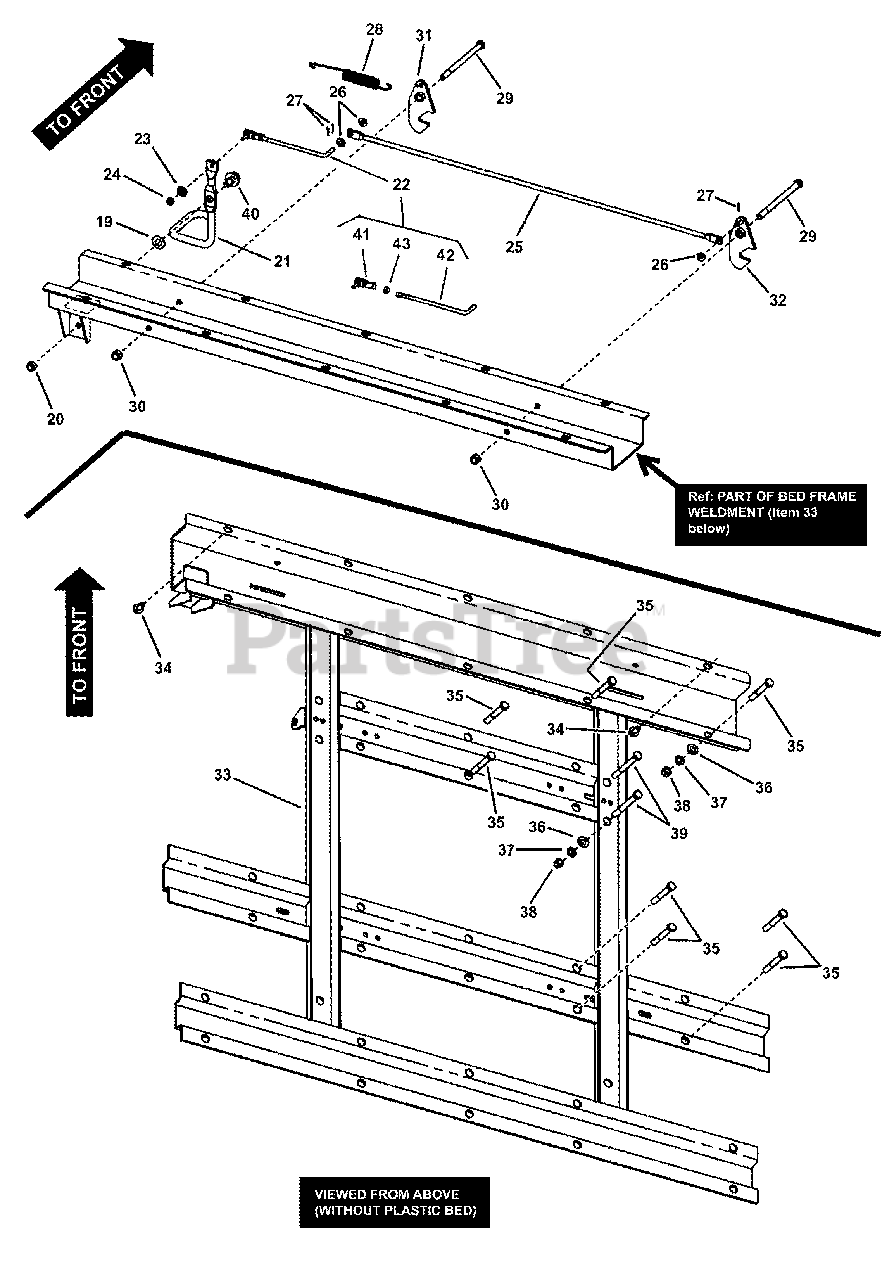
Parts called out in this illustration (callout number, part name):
19	WASHER, .5 x 1.0 x .03 Flat
20	NUT, Hex Nyloc, 3/8-24
21	HANDLE, Bed Latch
22	ASSEMBLY, Rod-Link (Includes Ref. Nos. 41, 42 & 43)
23	WASHER, 1/4 Internal Tooth Lock
24	NUT, Hex, 1/4-28 GR 5 or B
25	ROD, Link
26	WASHER, .28 x .63 x .06 Flat
27	COTTER PIN, .06 x .50
28	SPRING, Extension
29	CAPSCREW, Hex Head, 3/8-16 x 5-1/2 GR 5
30	NUT, Hex Nyloc, 3/8-16
31	HOOKASSEMBLY, Bed (weldment)
32	HOOKASSEMBLY, Bed (weldment)
33	BED FRAME ASSEMBLY
34	BOLT, Hex Flange Lock, 5/16-18 x 5/8 GR 5
35	CAPSCREW, Hex Washer Head, 3/8-16 x 2-1/2 GR 5
36	WASHER, 3/8 SAE Flat
37	WASHER, 3/8 Split Lock
38	NUT, Hex, 3/8-16 GR 5 or B
39	CAPSCREW, Hex Head, 3/8-16 x 3-1/4, GR 5
40	BOLT, Hex Flange, 3/8-24 GR 8
41	BALL JOINT, 1/4-28
42	ROD-LINK (1/4-28 thread)
43	NUT, Hex, 1/4-28 GR 5 or B
